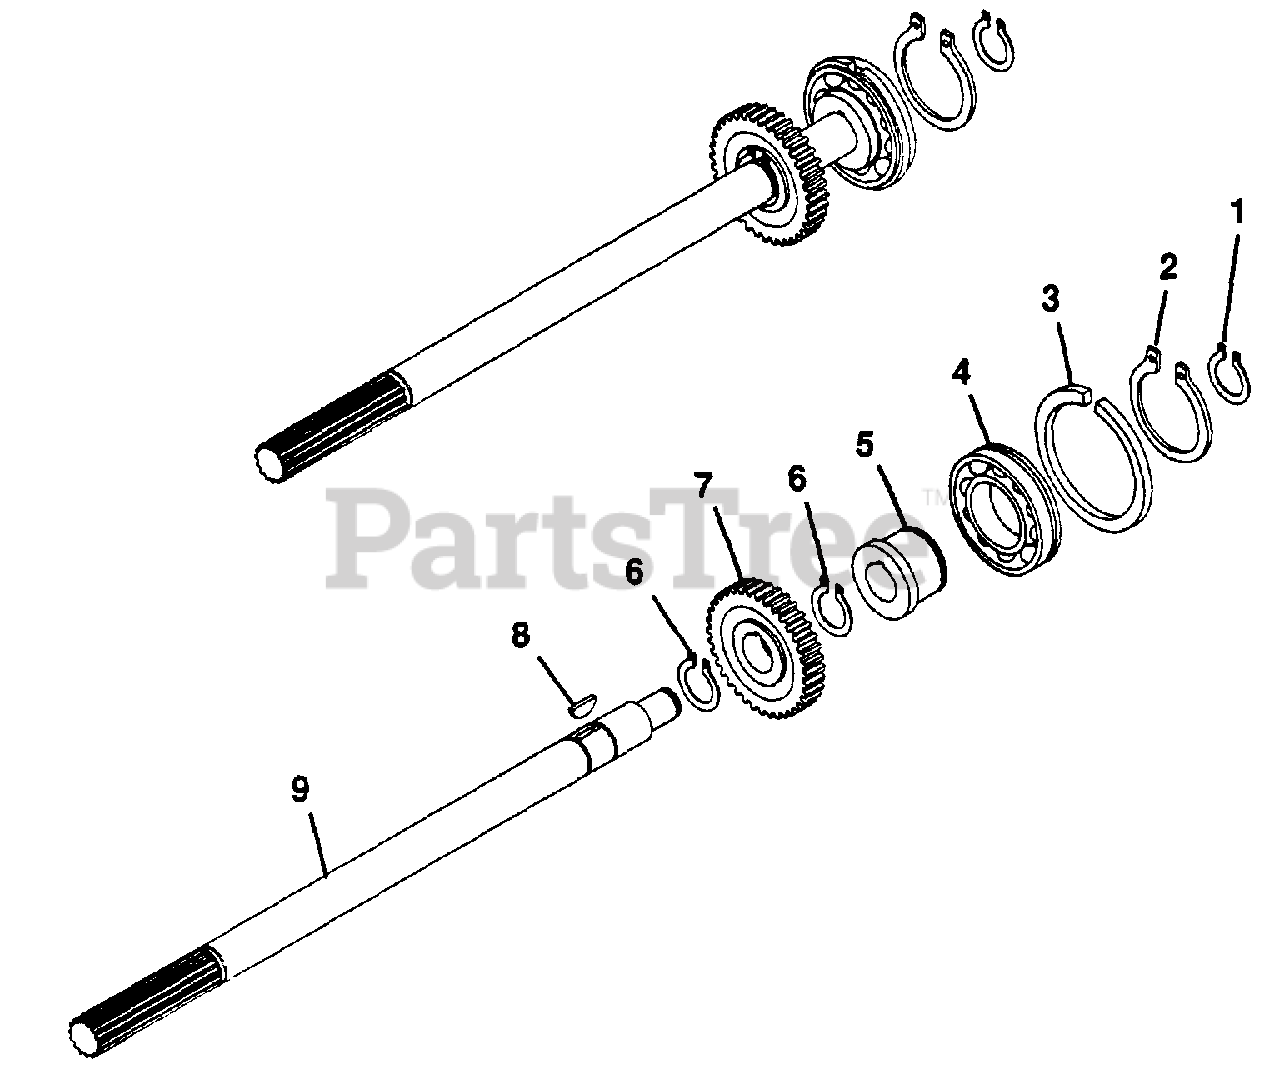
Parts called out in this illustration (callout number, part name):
1	Ring, Retaining .750 Shaft
2	Ring, Retaining
3	Ring, Retaining
4	Bearing, Ball 1.378x2.440x.551
5	Adapter, PTO Bearing
6	Ring, Retaining .984 Shaft
7	Gear, PTO Cross Shaft
8	Key, Woodruff .187x.750 Hrd #9
9	Shaft, PTO
